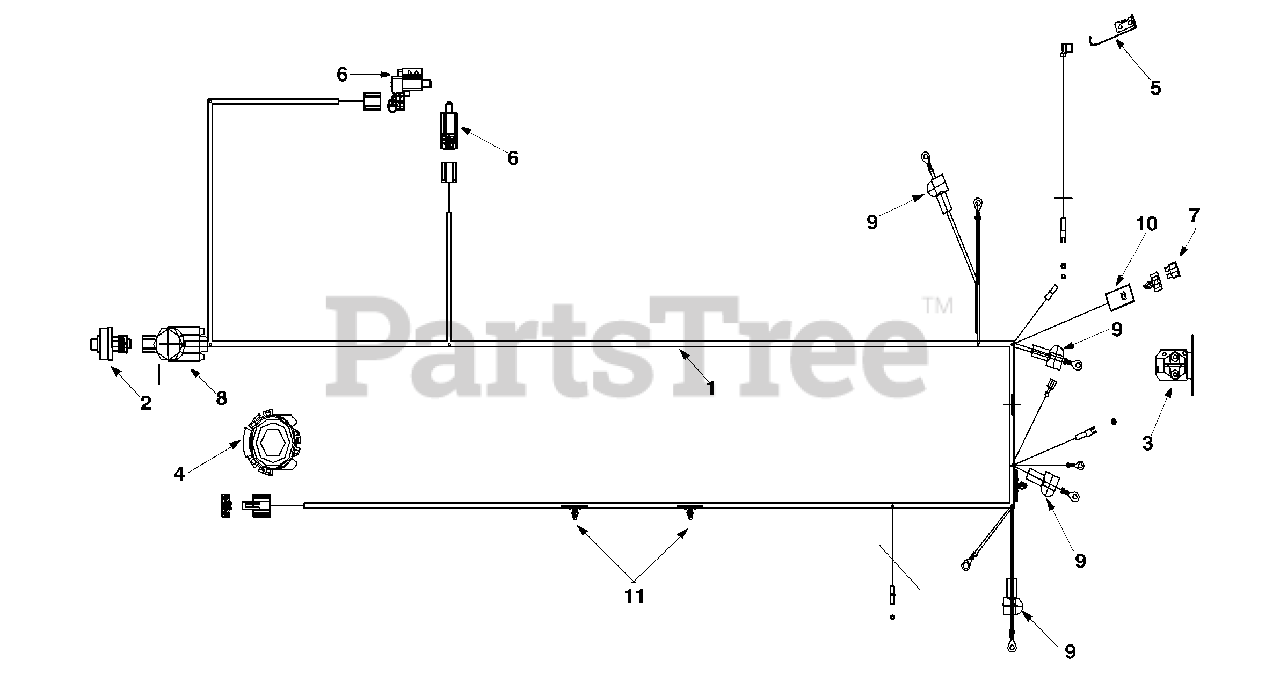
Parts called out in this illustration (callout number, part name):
1	Harness Assembly w/o relays
2	Ignition Switch: 5 Pin
3	Solenoid: 12 V. 100 amp.
5	Spring Switch
6	Interlock Switch
7	Fuse: 20 amp.
8	Battery Cover
9	Battery Cover: Red
10	Fuse Holder w/Clip
11	Harness Clip
